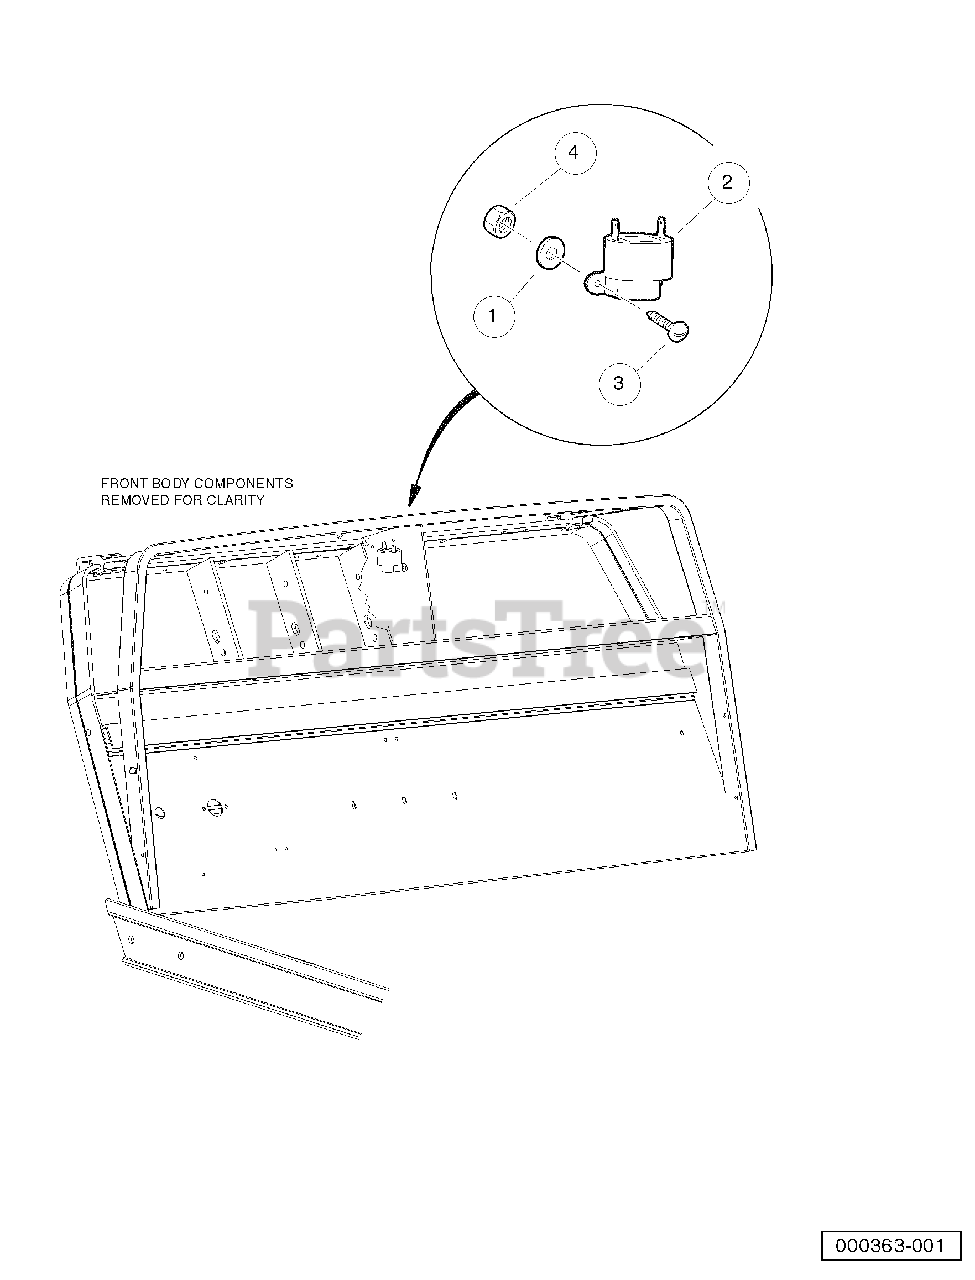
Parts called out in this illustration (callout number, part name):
1	Washer, #4 Flat
2	Buzzer, Reverse
3	Screw, #4-40 X 0.75 Round-Head Machine
4	Nut, #4-40 Hex Machine
